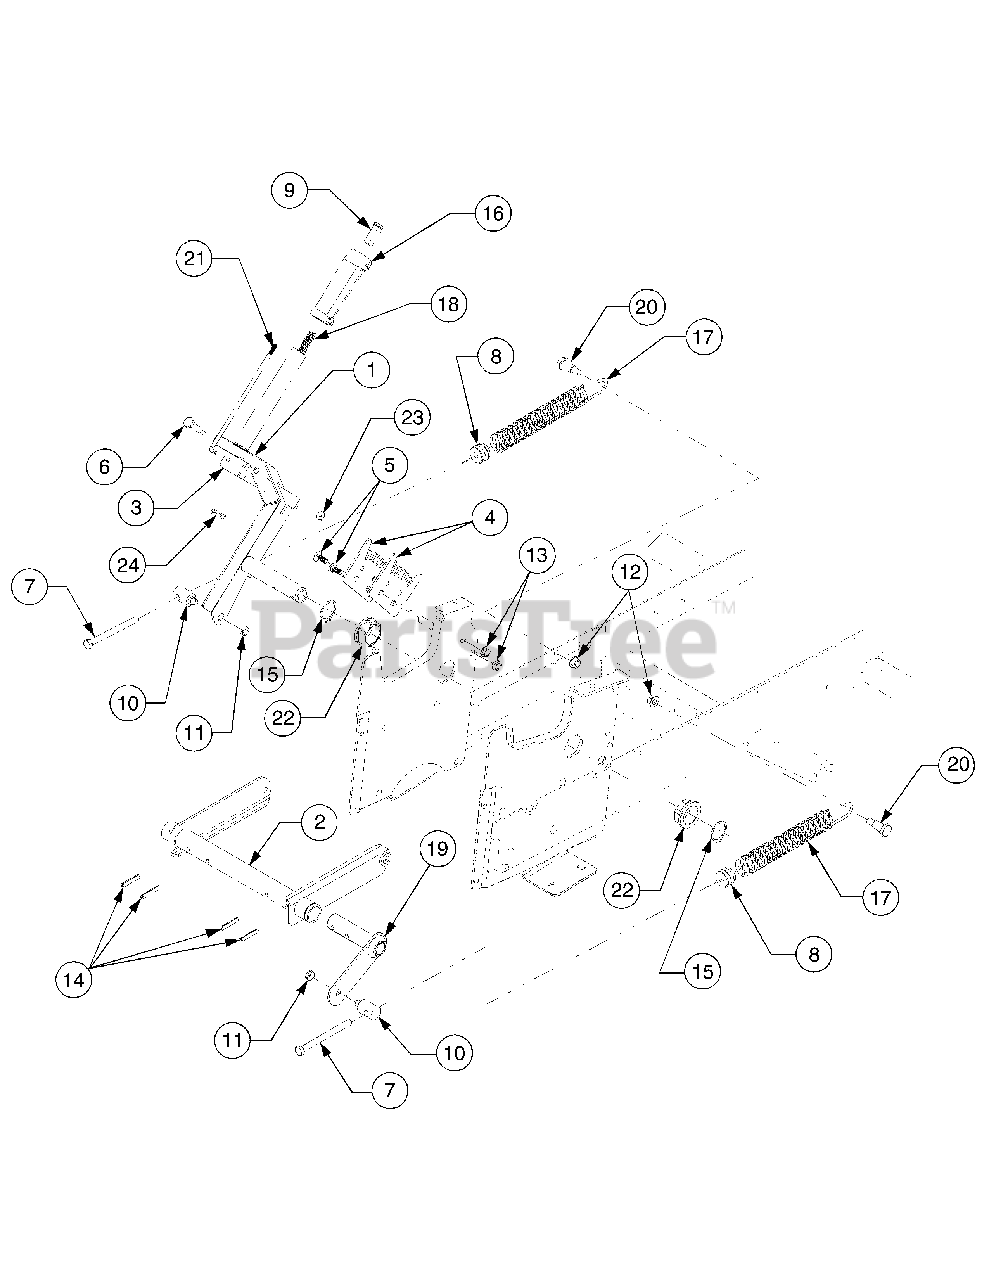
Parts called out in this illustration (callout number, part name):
5	Bolt, Carriage, 5/16-18 x .75
6	Screw, Shoulder, .374 x 1.375
7	Screw, Hex Cap, 3/8-16 x 4.25 GR5
8	Insert, Spring
9	Button, Handle
10	Ferrule, Adjustment
11	Nut, Hex Center Lock, Jam, 3/8-24
12	Nut, Hex Flanged Lock, 3/8-16
13	Nut, Hex Flanged Top Lock, 5/16-18
14	Pin, Spiral Spring, 1/4 Dia x 1.5
15	Ring, Snap, 1.25 Dia Shaft
16	Grip, Lift Handle
17	Spring, Extension
18	Spring, Compression
20	Bolt, Shoulder
21	Rod, Index
22	Bearing, Hex Flange, 1.25 ID
23	Nut, Hex Flange Lock, 1/4-20
24	Pin, Internal Cotter
